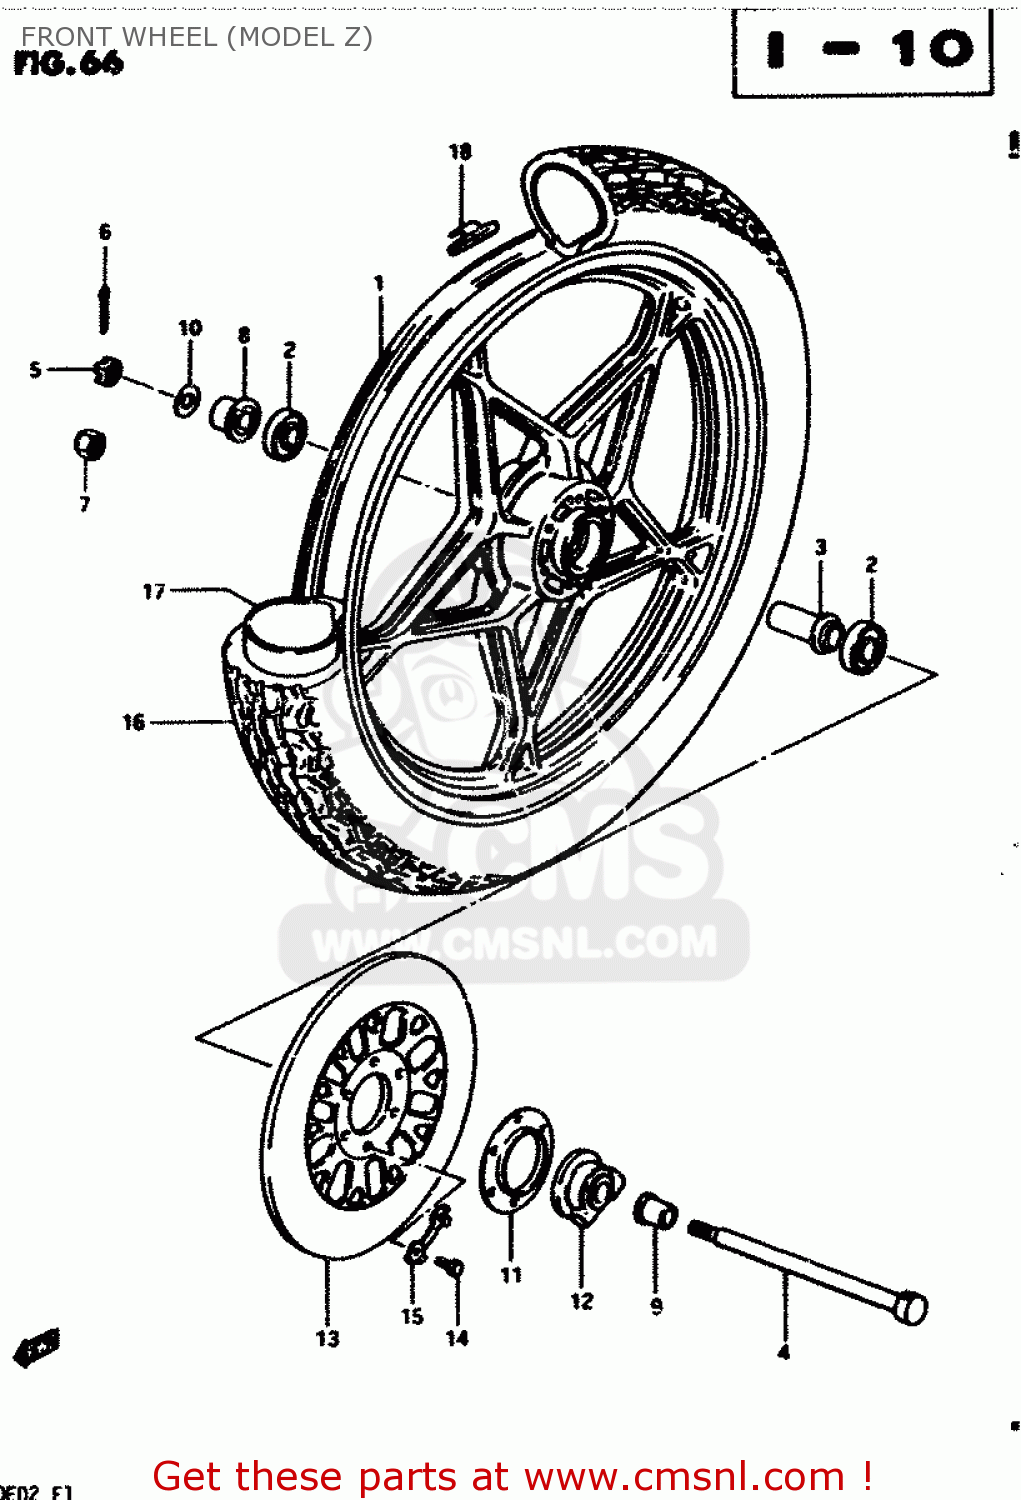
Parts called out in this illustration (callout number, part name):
1	CASTING WHEEL,FRONT 1.60
2	BEARING
3	SPACER(15.3X21.7X63)
4	AXLE,FRONT
5	NUT 12MM
6	COTTER PIN
7	NUT
8	SPACER,FR HUB BEARING,R
9	SPACER(15X22X30)
10	WASHER
11	DUST SEAL,SPEEDOMETER GEAR BOX
12	BOX ASSY,SPEEDOMETER GEAR
13	DISC,FR BRAKE
14	BOLT(8X25)
15	WASHER
16	TIRE,FRONT
17	TUBE,INNER
18	BALANCER,WHEEL
